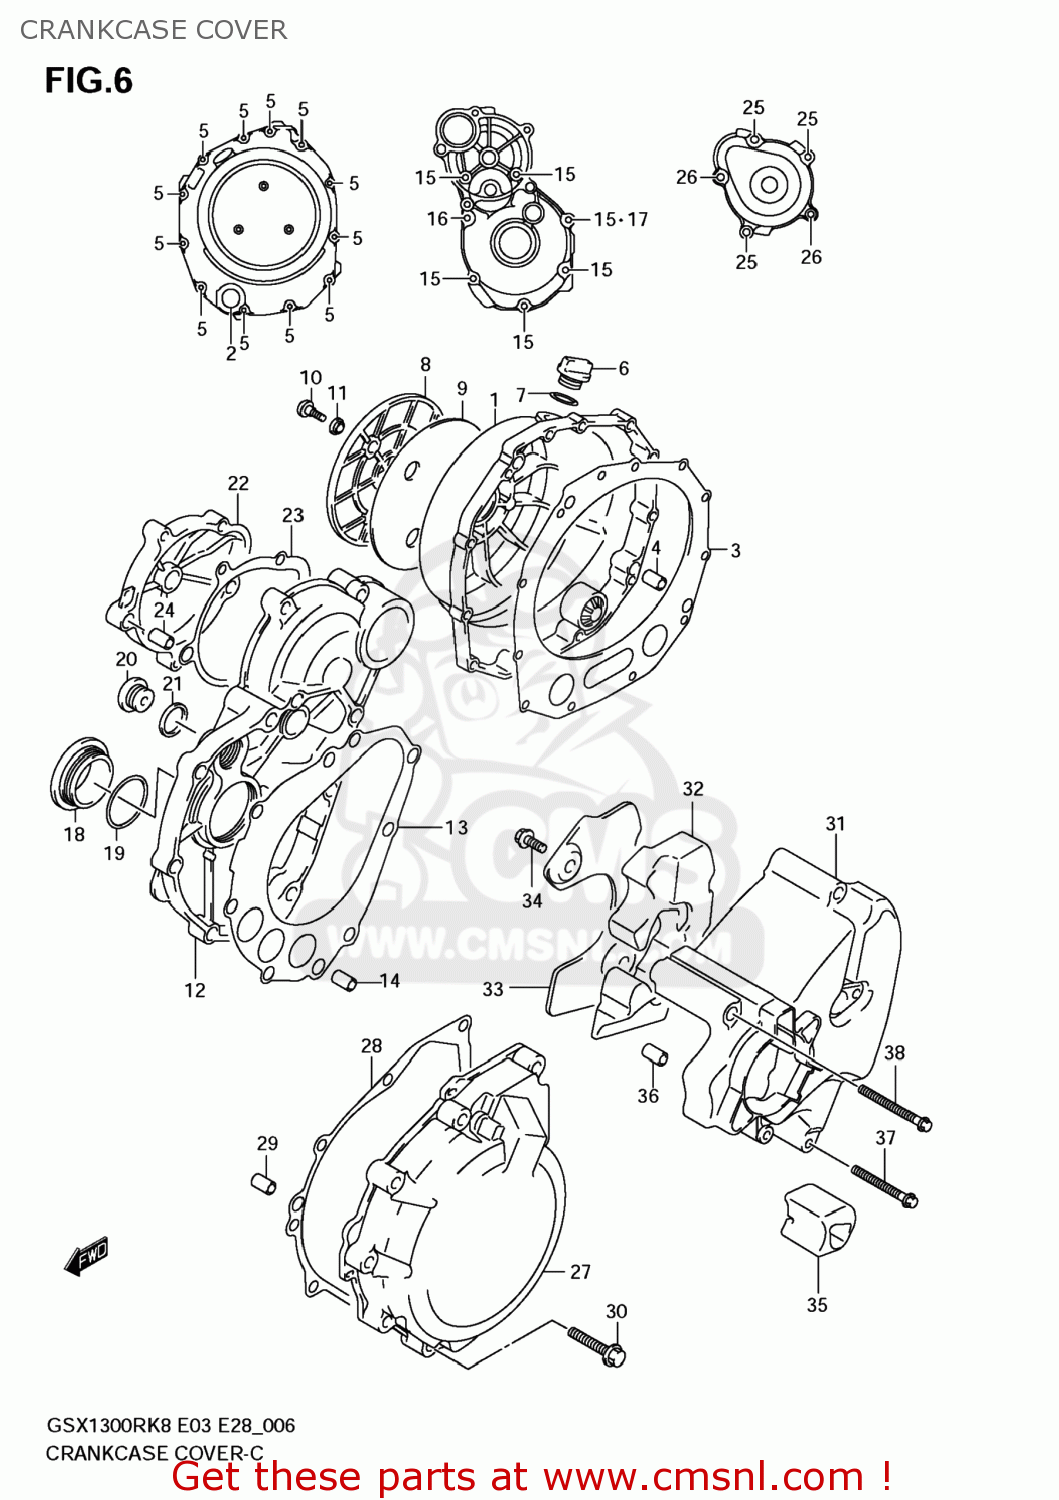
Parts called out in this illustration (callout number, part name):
1	COVER,CLUTCH
2	LENS,OIL LEVEL CHECK
3	GASKET,CL COVER (NAS)
4	PIN
5	BOLT(6X30)
6	PLUG,ENGINE OIL FILLER
7	O RING(D:3.1,ID:16.8)
8	COVER,CLUTCH OUTER
9	CUSHION,CLUTCH OUTER COVER
10	SCREW(6X16)
11	WASHER,CLUTCH OUTER COV SCREW
12	COVER,STARTER CLUTCH
13	GASKET,STARTER CLUTCH COVER (NAS)
14	PIN
15	BOLT(6X25)
16	BOLT(6X35)
17	GASKET(5.8X13X1.2) (NAS)
18	PLUG
19	O RING(D:3.1,ID:32.7)
20	PLUG,16X8
21	GASKET(16X22X2) (NAS)
22	CAP,STARTER IDLE GEAR
23	GASKET,START IDLE GEAR CAP (NAS)
24	PIN
25	BOLT(6X25)
26	BOLT(6X35)
27	COVER,MAGNETO
28	GASKET,MAGNETO COVER (NAS)
29	PIN
30	BOLT(6X30)
31	COVER,ENGINE SPROCKET
32	DAMPER,ENG SPROCKET COVER
33	PLATE,ENGINE SPROCKET COVER
34	BOLT(6X12)
35	PROTECTOR,ENGINE SPRKT COVER
36	PIN
37	BOLT(6X55)
38	BOLT(6X65)
